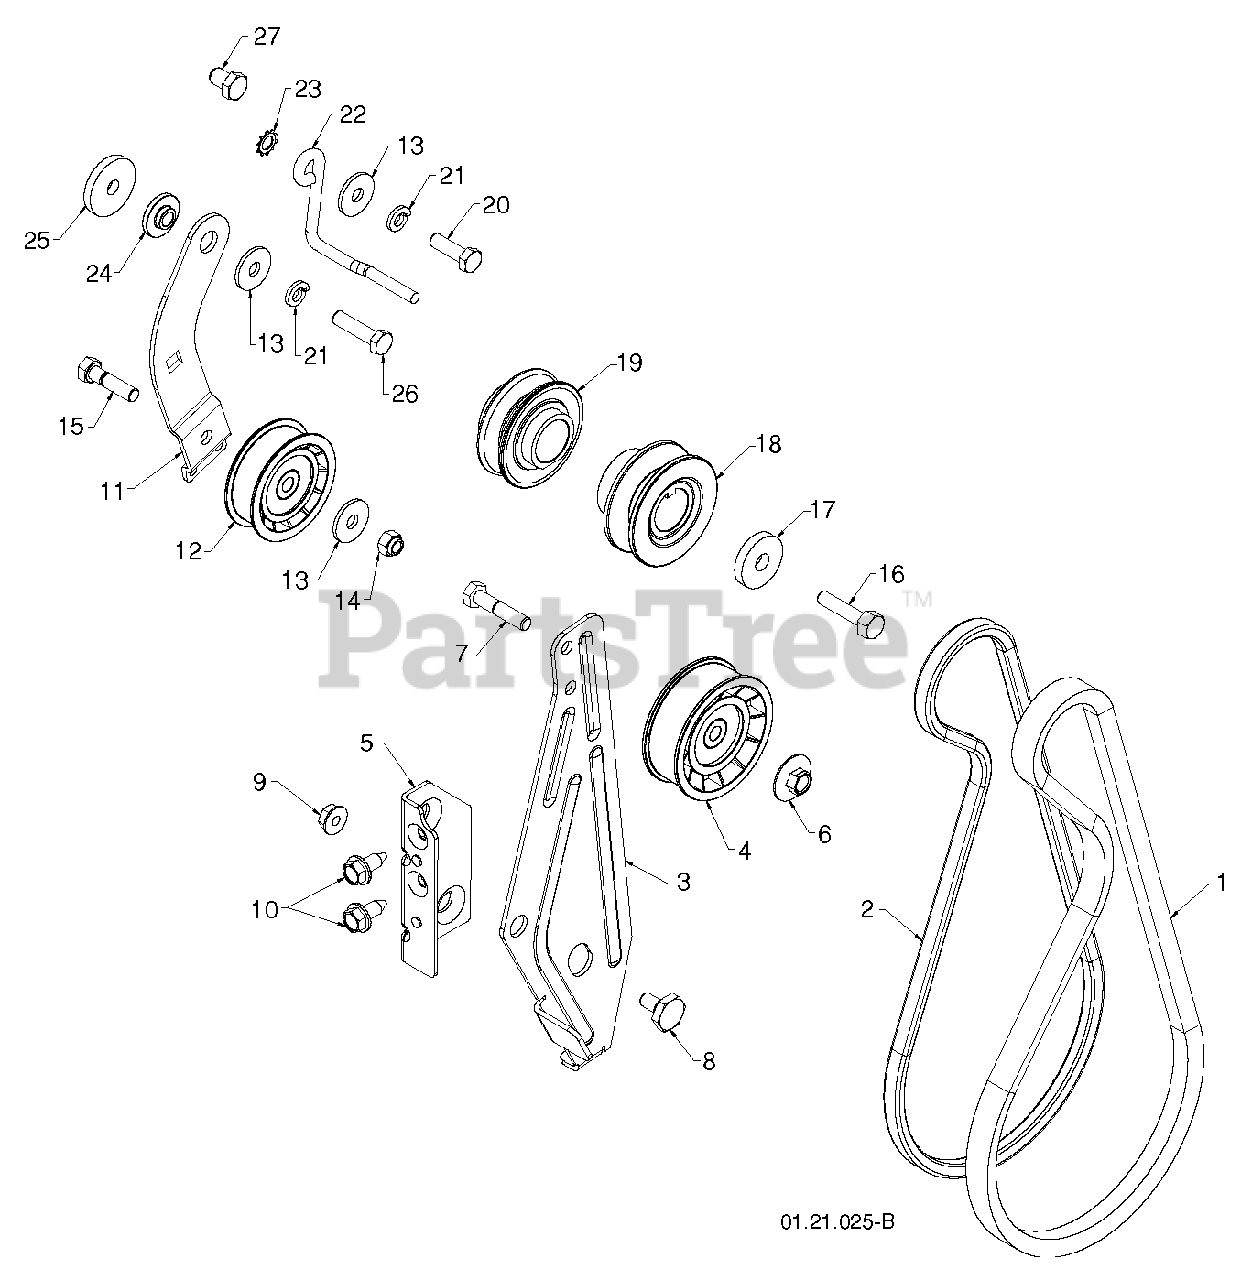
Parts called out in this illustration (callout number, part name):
1	V-BELT.IMPELLER
2	BELT.4L.1/2X35
3	ARM.IDLER.BRAKE.
4	PULLEY.W/SPACER.2.75
5	RP BRACKET.IDLER.PIVOT
6	NUT.FLANGE.HEX.5/16X18.BLACK
7	HEX BOLT
8	BOLT.SHOULDER.1/2X12
9	NUT.LOCK.5/16-18
10	BOLT.5/16HEX.WHS.HD
11	RP ARM.ASM.TRACTION.IDLER
12	PULLEY.W/SPACER.2.25
13	STEEL WASHER
14	NUT.71038.31-18.HEX.NYLOCK
15	BOLT.5/16-18X1-1/4 FULL.THREAD
16	SCREW, HEX HD 3/8-24 X 1-3/8
17	WASHER.400X1.25X5.
18	PULLEY ENG IMPELLER
19	PULLEY.ASM.ENG.TRACTION.1.00
21	LOCKWASHER
22	BELT.GUIDE.SNOW.YELLOW.ZINC
23	WASHER EXT TOOTH LOCK 5/16
24	RP BUSHING, IDLER PIVOT
25	WASHER.FLAT.34X1.38X22
26	CAPSCREW.HEXHD.5/16X1.25.
27	SCREW.3/8-16 X .750 (2 2)
